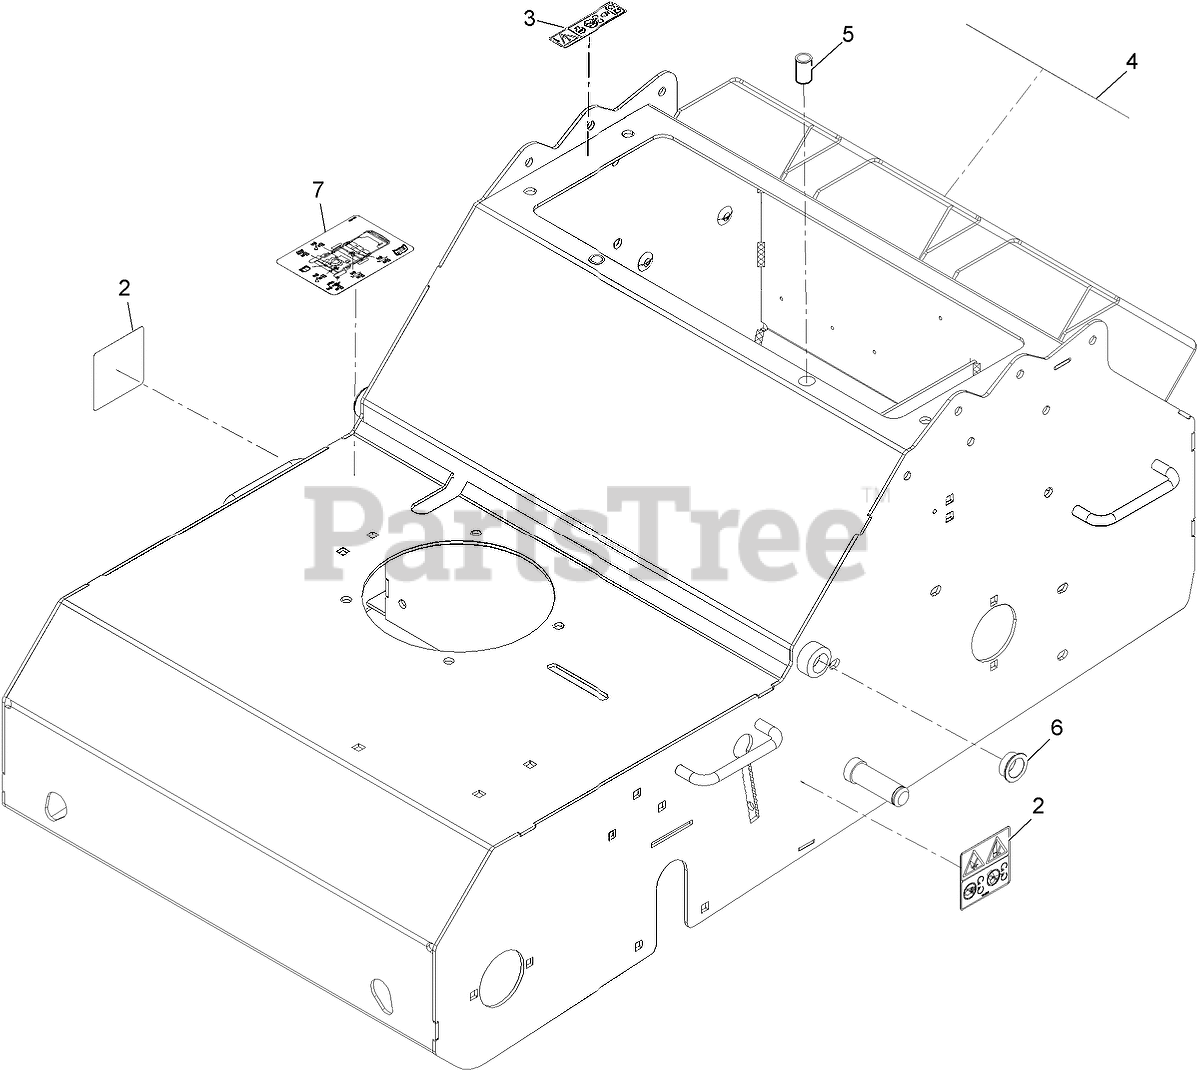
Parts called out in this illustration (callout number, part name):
2	DECAL-WARNING
3	DECAL-DANGER
4	Decal-Warning Aerator 21
5	NUT-CLINCH
6	BUSHING-BRONZE
7	Decal-Service Aid 21 Aerator
